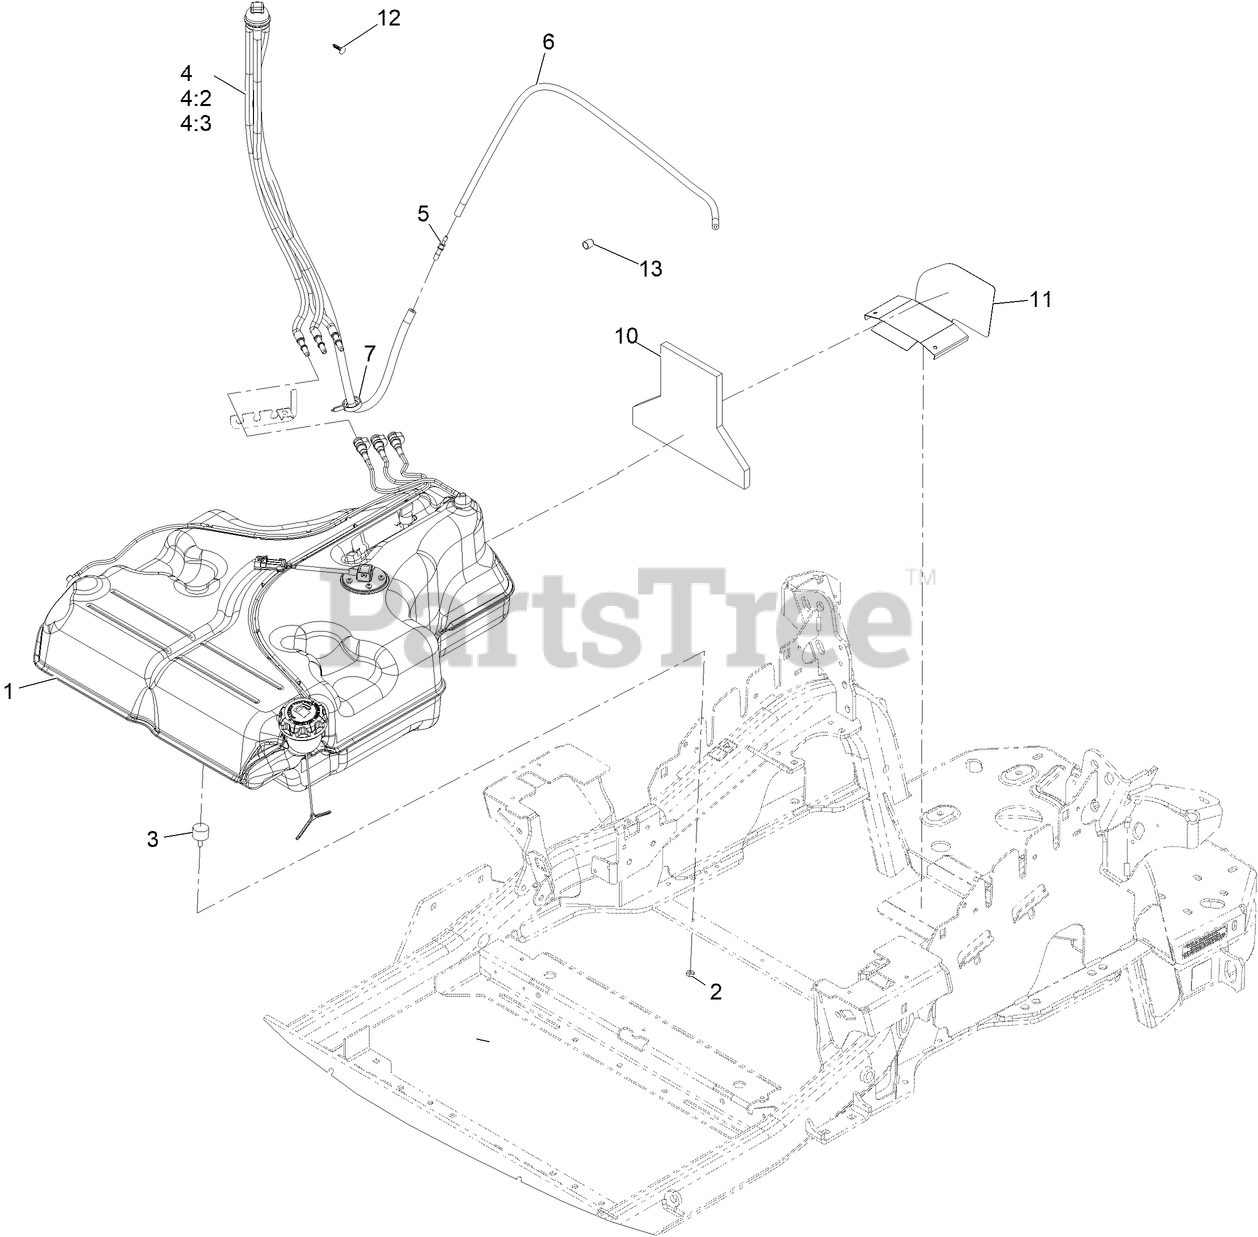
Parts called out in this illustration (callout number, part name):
1	FUEL TANK ASM
2	NUT-JAM
4	FUEL MANIFOLD VENT ASM
4:2	HOSE-FUEL
4:3	HOSE-FUEL
5	BARB-FUEL
6	HOSE-FUEL
7	CLAMP-HOSE
10	INSULATION-FOAM, FUEL TANK
11	GUARD-EXHAUST
12	PLUG-PLASTIC
13	PLUG-PORT
